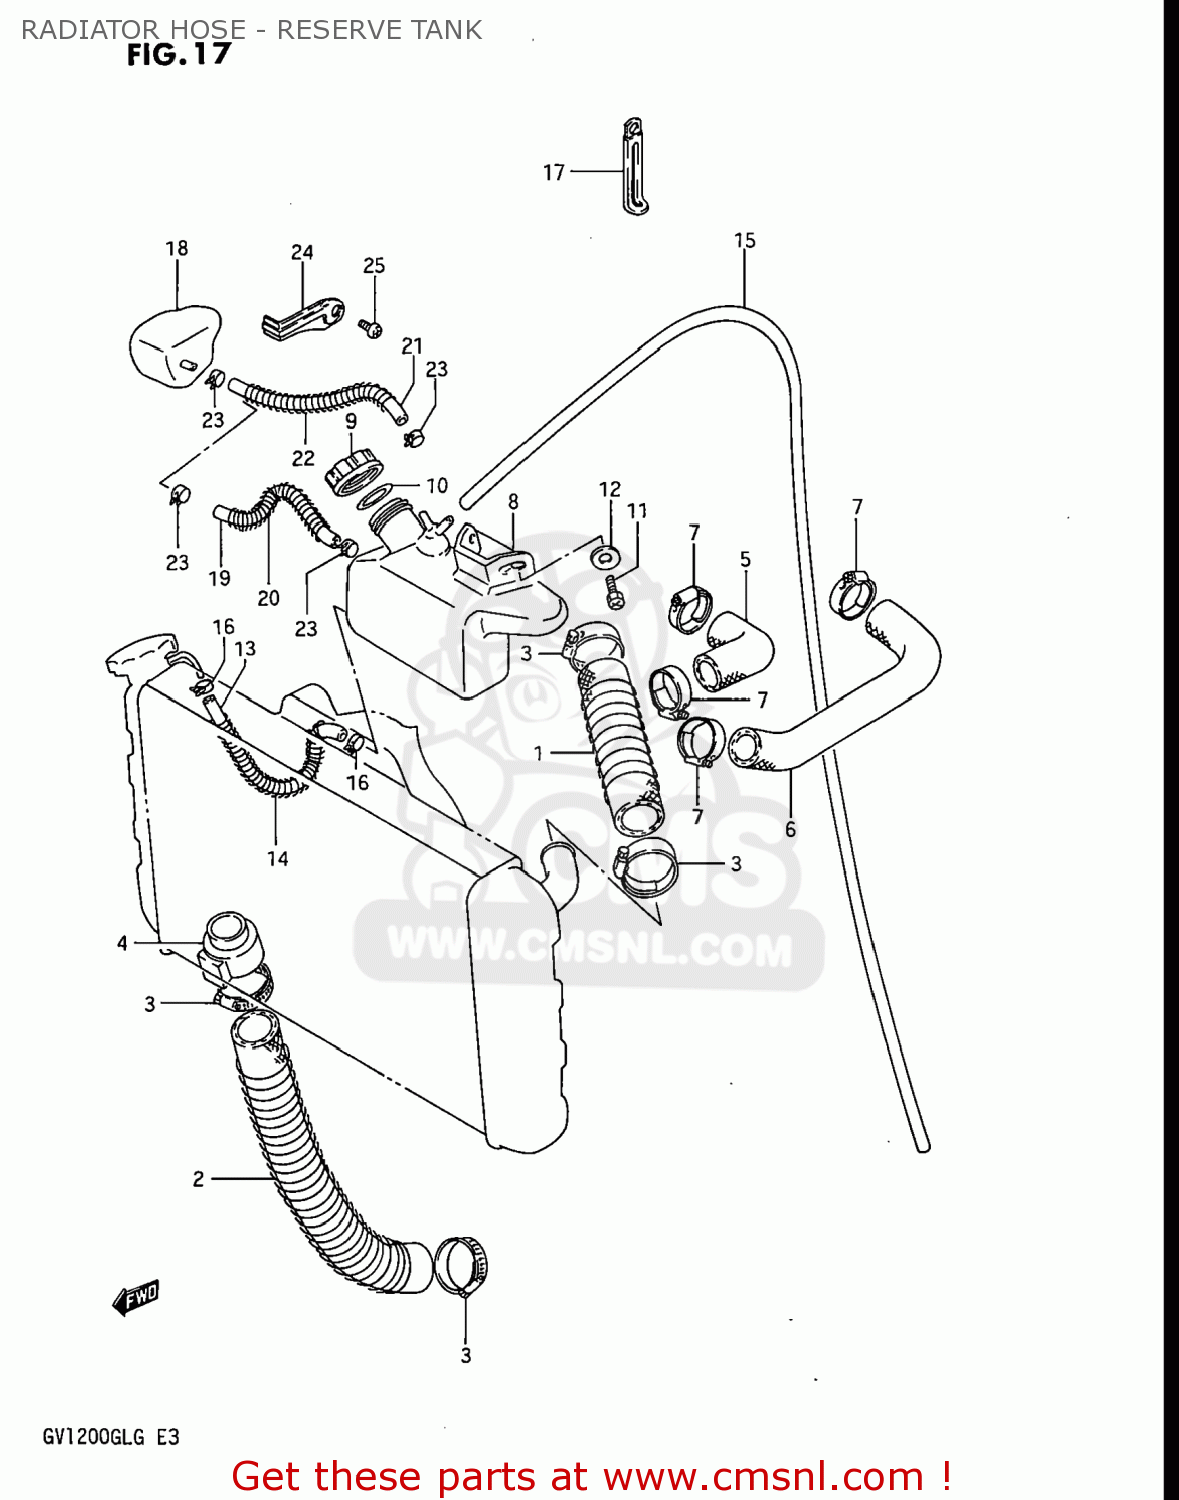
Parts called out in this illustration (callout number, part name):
1	HOSE,RADIATOR INLET
2	HOSE,RADIATOR OUTLET
3	CLAMP
4	HOSE,WATER
5	HOSE,THERMO IN FR
6	HOSE,THERMOMETER,IN,REAR
7	CLAMP
8	TANK,RESERVE
9	CAP,RESERVOIR TANK
10	GASKET,RESERVOIR TANK CAP (NAS)
11	SCREW
12	WASHER
13	HOSE,RESERVOIR TANK INLET
14	SPRING
15	HOSE
16	CLIP
17	CLAMP
19	HOSE,RESERVOIR INLET
20	SPRING
22	SPRING
23	CLIP
25	SCREW
